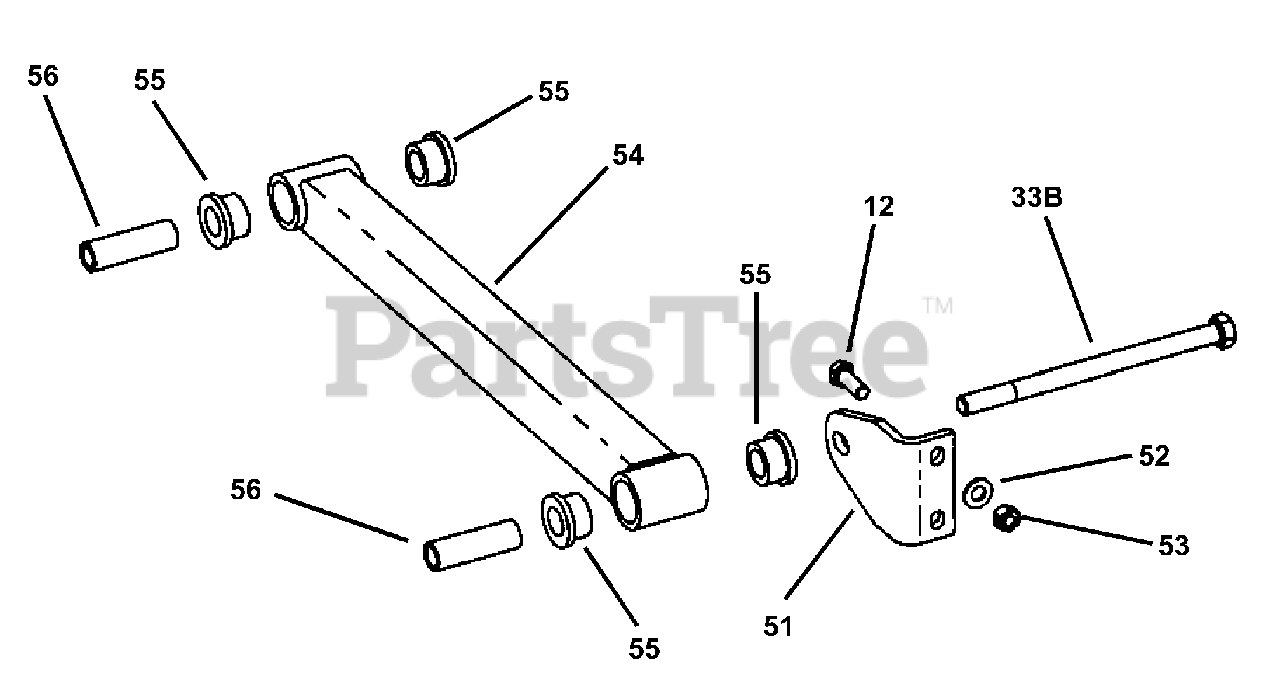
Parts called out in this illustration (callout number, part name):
12	BOLT, 3/8-16 X 1" GD5 CZ
33B	BOLT, 1/2-13 X 7-1/2" GD5 YZ
51	BRACKET, Deck Stabilizer
52	WASHER, 3/8" Flat
53	NUT, 3/8-16 Hex Center Lock
54	STRUCTURE, 61" Stabilizer Bar
55	BUSHING, Suspension
56	SLEEVE, Suspension
